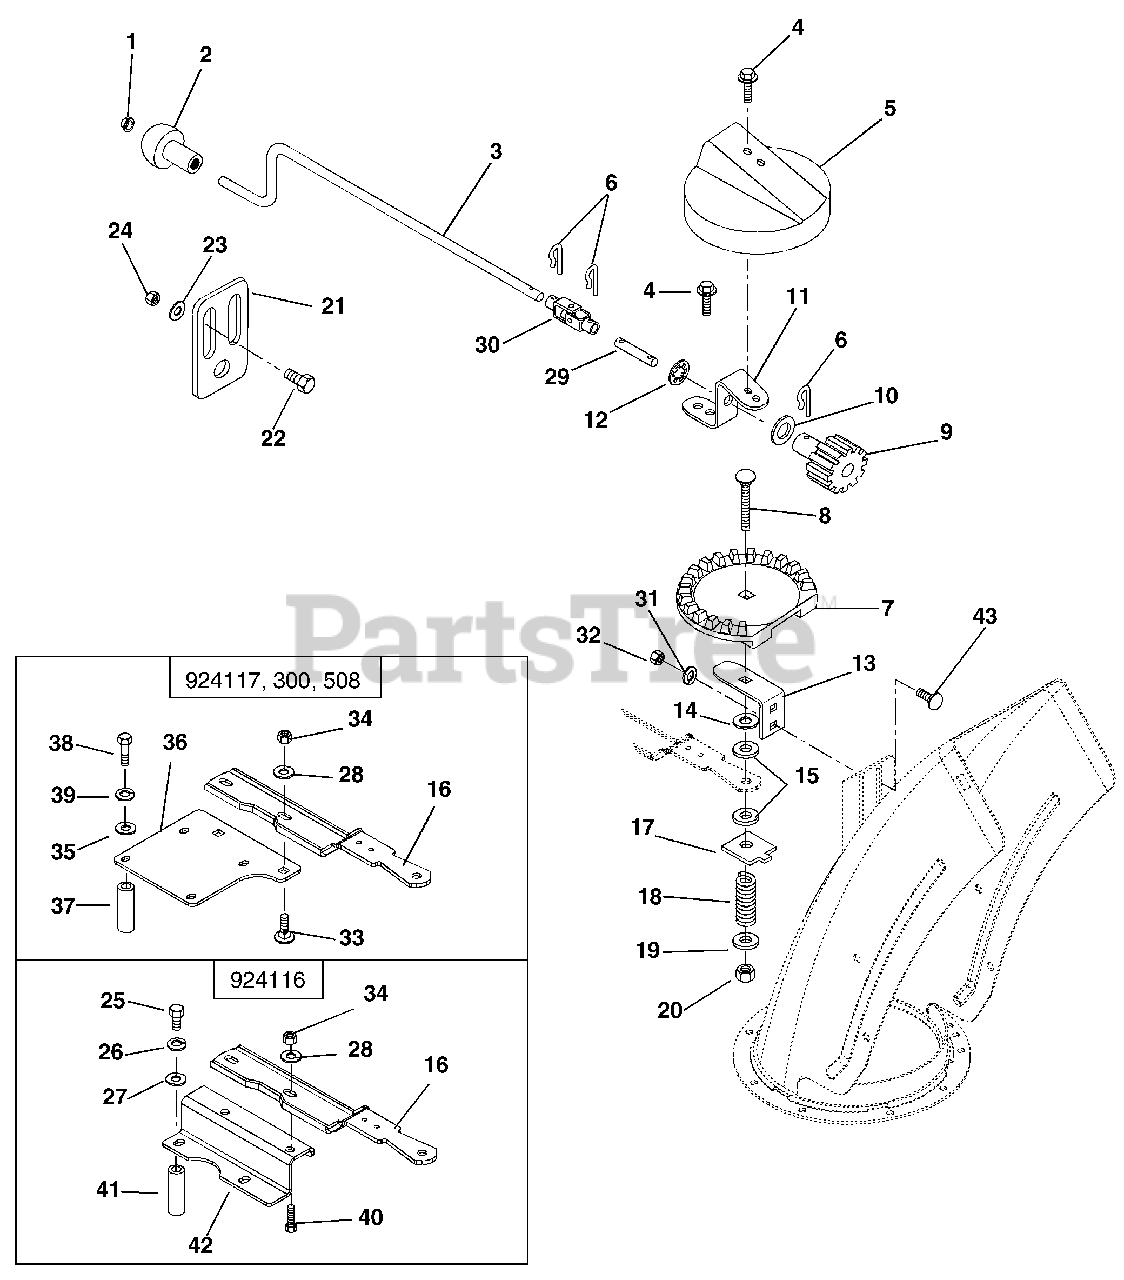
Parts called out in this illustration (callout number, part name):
1	CAP, 3/8 ROD YWZC
3	CRANK, CHUTE
4	@SCR-TAP .25-20X.50 HWH TR YWZ
5	GEAR COVER
6	PIN, SPRING CLIP
7	CHUTE GEAR
8	@BLT-RDHDSQNK .38-16X2.50 G5YZ
9	PINION GEAR W/BRACKET
10	WSHR-FL-STL .630X1.005X.062 YZ
11	BRACKET-GEAR
12	PUSHNUT .625
13	GEAR STRAP
14	WSHR-FL-STL .380X1.50X.062 YWZ
15	FRICTION WASHER
16	BRACKET, CHUTE SUPPORT
17	FRICTION PLATE
18	SG-COMP .187X.56X1.62
19	@WSHR-FL-STL.406X.812X.065 YWZ
20	@NUT-LK-CTR .38-16 YWZC
21	BRACKET, CHUTE CRANK SUPPORT
22	@BLT-HEX .25-20X.50 GR5 YWZC
23	@WSHR-FL-STL.312X.734X.065 YWZ
24	@NUT-LK-CTR .25-20 YWZC
25	@BLT-HEX .31-18X1.25 GR5 YWZC
26	WSHR-LK .312X.097 HVY YWZC
27	@WSHR-FL-STL.344X.688X.065YWZC
28	@WSHR-FL-STL.312X.734X.065 YWZ
29	PIN, CONNECTOR
30	UNIVERSAL JOINT ASS'Y
31	@WSHR-LK .25X.062 REG YWZC
32	@NUT-HEX .25-20 YWZC
33	@BLT-RDHDSQNK .31-18X.75 G5YZ
34	@NUT-LK-CTR .31-18 YWZC
35	@WSHR-FL-STL.281X.62X.065 YWZC
36	BRACKET, ENGINE
37	SPACER, TUBE
38	@BLT-HEX .25-20X.75 GR5 YWZC
39	@WSHR-LK .25X.062 REG YWZC
40	@BLT-HEX .31-18X.75 GR5 YWZC
41	SPACER .322X.626X.50
42	BRACKET, ENGINE-8&10
43	@BLT-RDHDSQNK .25-20X.75 G5YZ
